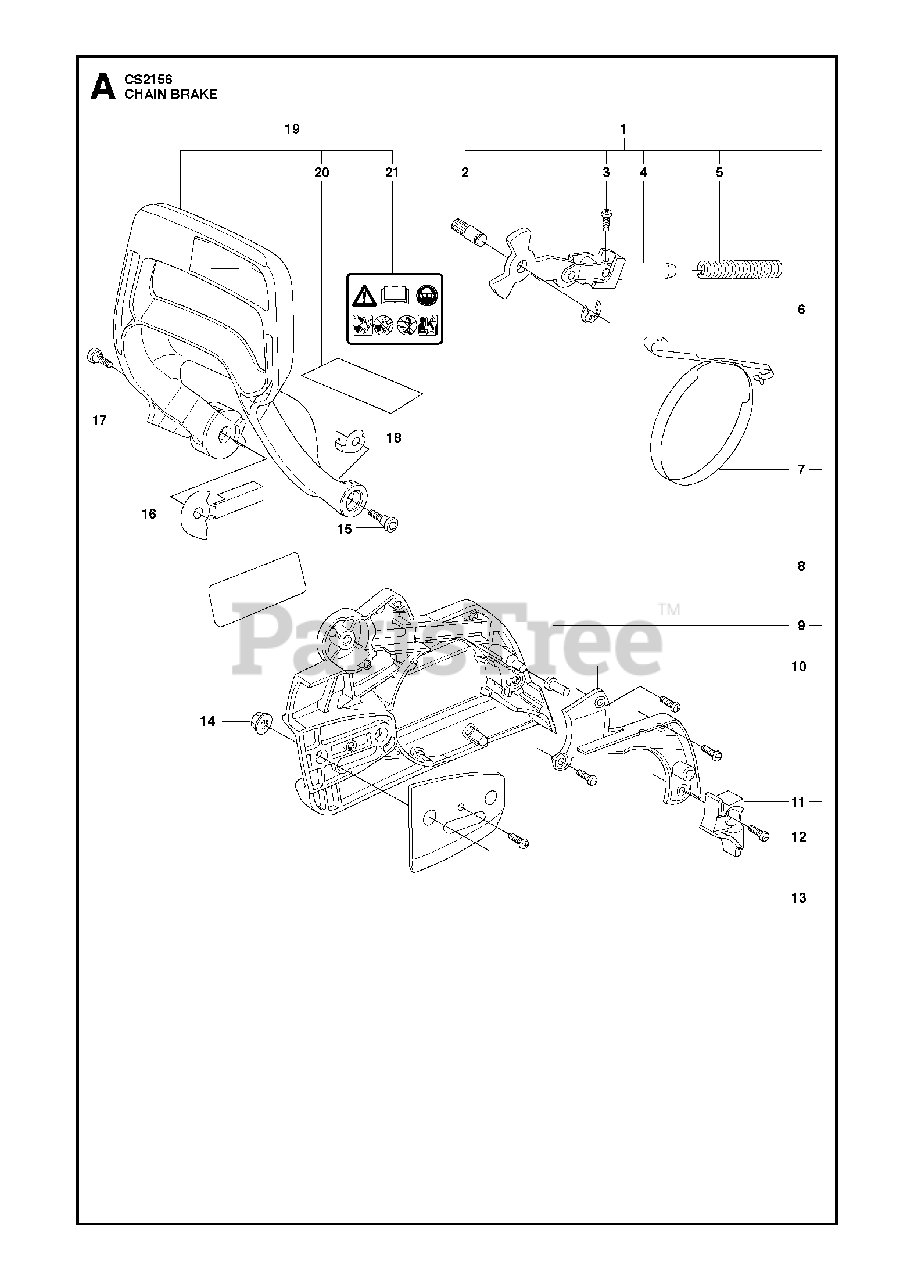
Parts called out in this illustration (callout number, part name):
1	CHAIN BRAKE
2	PIN
3	SCREW
4	JOINT
5	SPRING
6	E-RING 4
7	BRAKE BAND
8	DECAL
9	SLEEVE
10	COVER
11	PROTECTOR
12	SCREW
13	PLATE
14	NUT M8 FLANGE
16	PROTECTOR
19	HAND GUARD
20	PROTECTOR
21	DECAL
